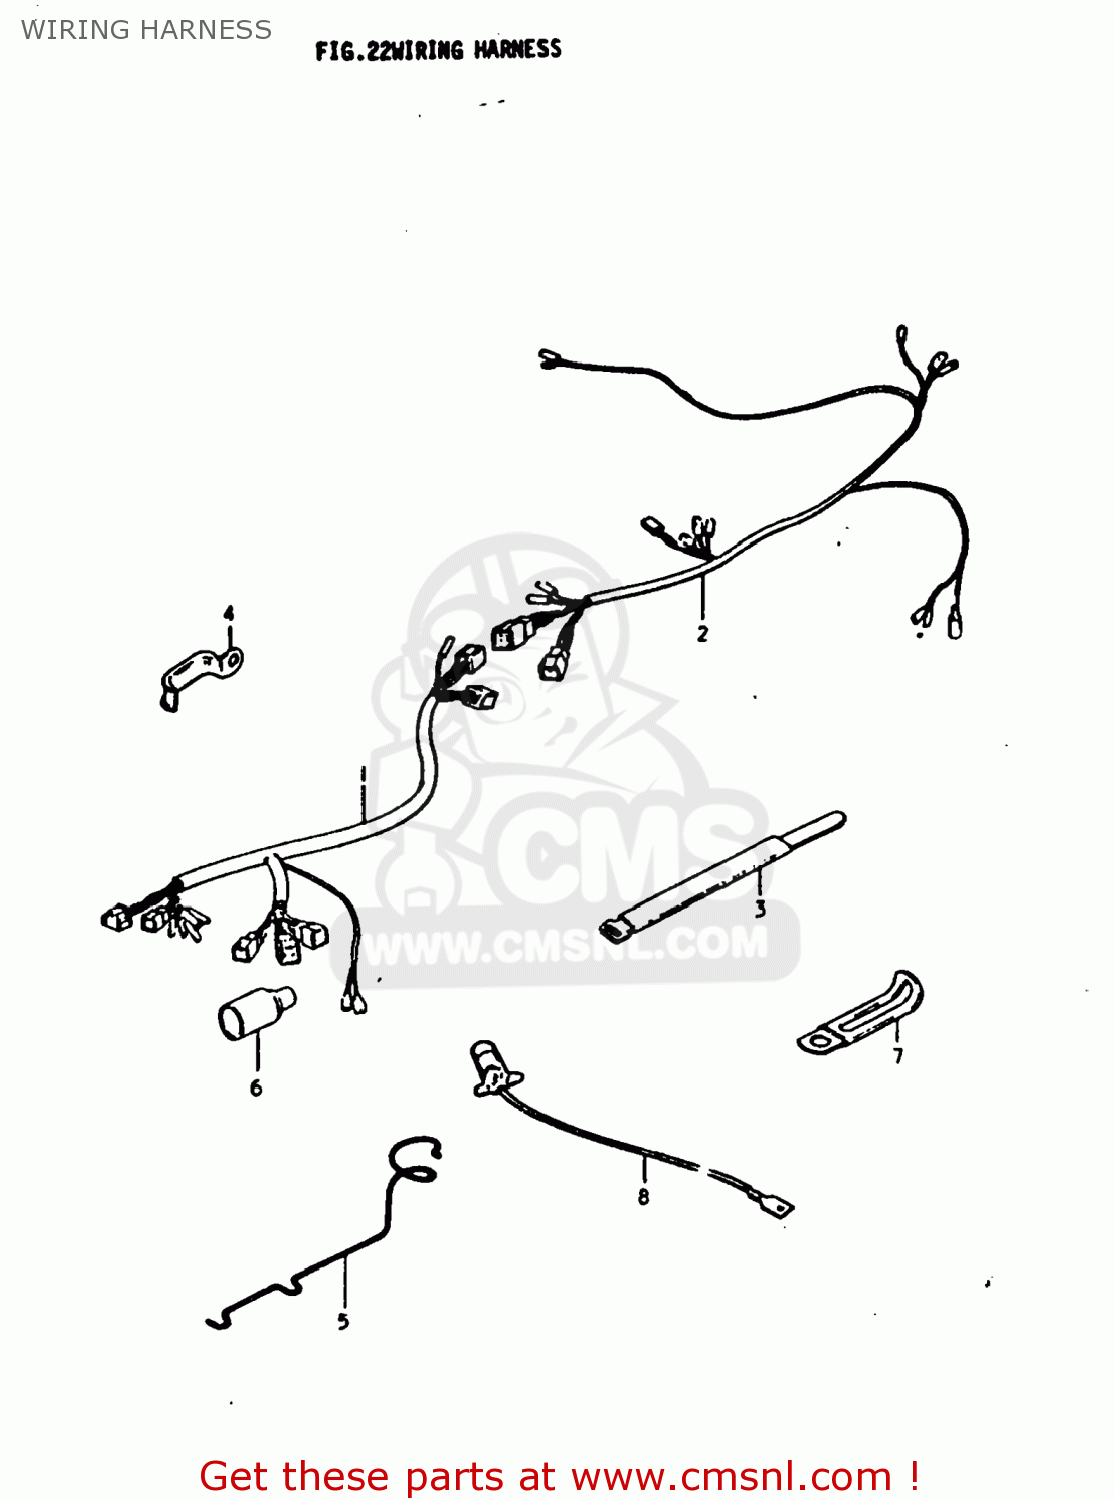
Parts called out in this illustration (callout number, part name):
1	HARNESS,WIRING
2	HARNESS,WIRING NO.2
3	CLAMP
4	CLAMP
5	GUIDE,WIRING HARNESS
6	BOOT,WIRING HARNESS
7	CLAMP
8	WIRE,WIRING HARNESS LEAD
